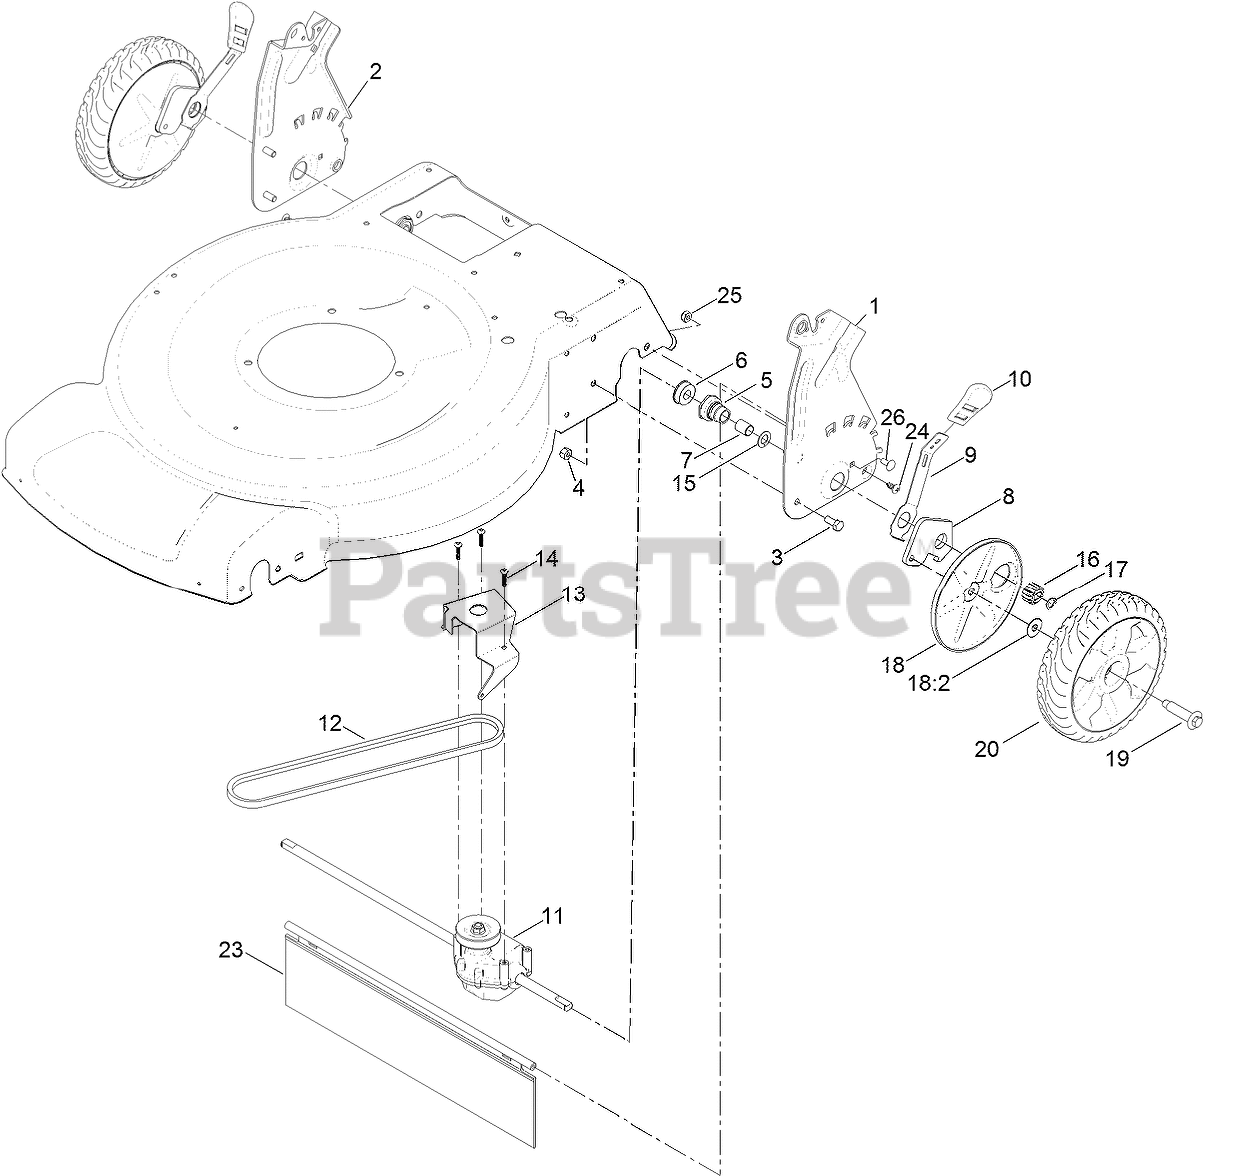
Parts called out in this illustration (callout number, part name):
1	PLATE-REAR, LH (HOC)
2	PLATE-REAR, RH (HOC)
3	SCREW-HH
4	NUT-LOCK, NI
5	RETAINER-BUSHING, HOC
6	BEARING-BALL
7	BUSHING-SLEEVE
8	ARM-PIVOT, REAR
9	ARM-SPRING
10	KNOB-HOC
11	TRANSMISSION ASM
12	BELT-V
13	BRACKET-TRANSMISSION
14	SCREW-PLASTITE
15	WASHER-THRUST
16	GEAR-PINION, 15T
17	RING-RETAINING
18	WHEEL COVER ASM
18:2	WASHER-STEPPED
19	BOLT-SHOULDER
20	8 INCH WHEEL GEAR ASM
23	SHIELD-TRAILING
24	SCREW-PTH
25	SCREW-CARR
26	NUT-LOCK, NI
